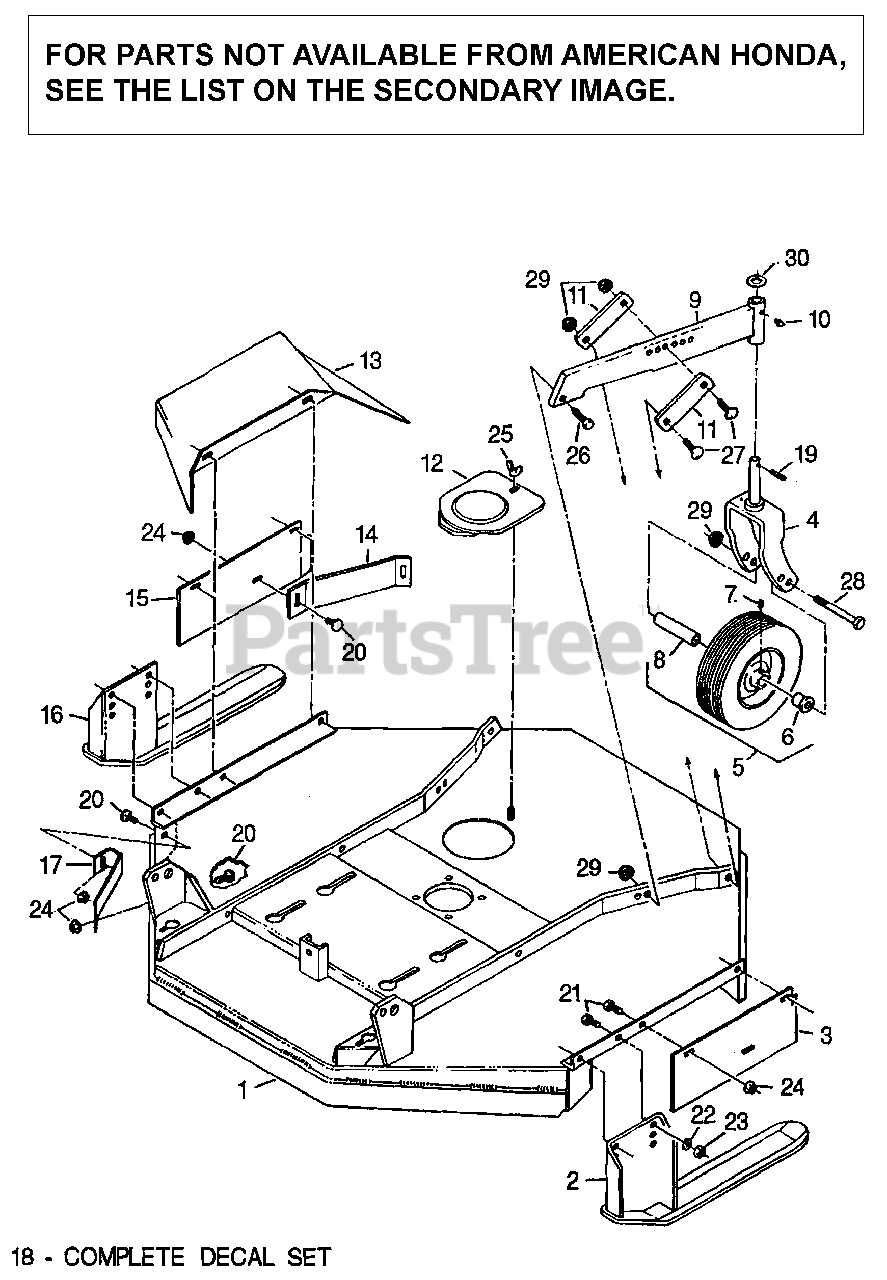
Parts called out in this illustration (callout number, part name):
2	SKID, L. SIDE
3	SHIELD, L. SIDE
4	YOKE ASSY.
5	WHEEL, CASTER (10-1/4)
6	BEARING, FLANGE
8	SLEEVE (1/2 X 3/4 X 3-3/8) (NOT AVAILABLE)
8	SLEEVE (1/2 X 3/4 X 3-3/8)
9	ARM ASSY., CASTER
11	BRACKET, CASTER ARM ADJUSTMENT
12	COVER ASSY., ACCESS HOLE
13	CHUTE, DISCHARGE
14	BAFFLE, SIDE SHIELD
15	SHIELD, R. SIDE
16	SKID, R. SIDE
17	BAFFLE, FR.
18	DECAL SET
19	PIN, SPIRAL
24	NUT, LOCK
28	SCREW, CAP HEX.
29	NUT, LOCK
